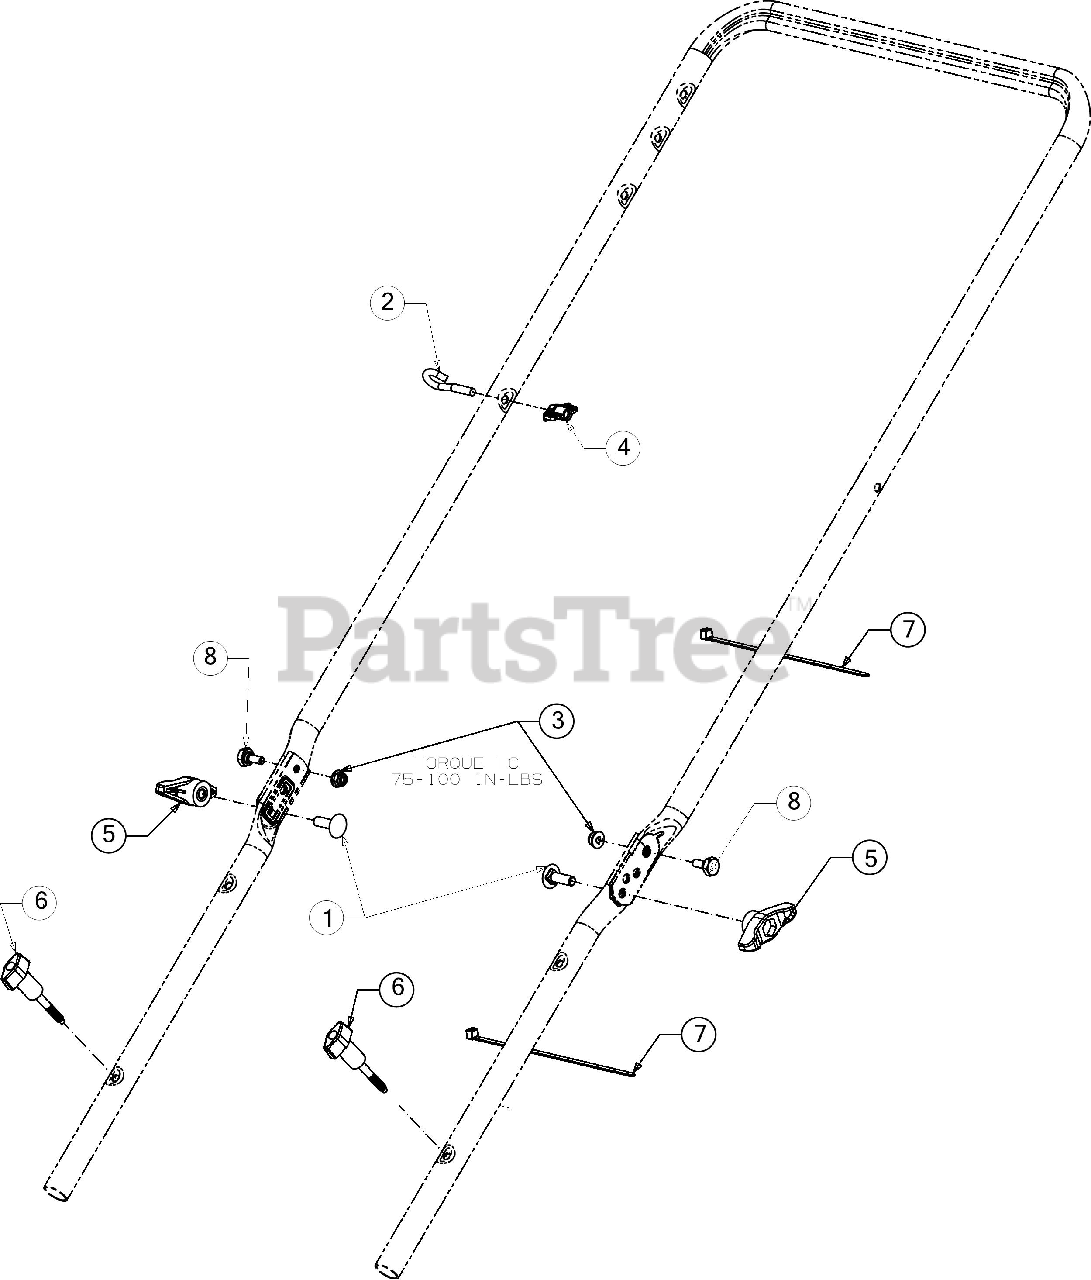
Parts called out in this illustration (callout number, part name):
1	SCREW 5/16-18 X 1.00 GR5
2	EYEBOLT 1/4-20
3	FLANGE LOCK NUT
4	HANDLE KNOB
5	WING KNOB 5/16-18
6	WING KNOB 1/4-20
7	CABLE TIE 7"
8	SHOULDER SCREW
